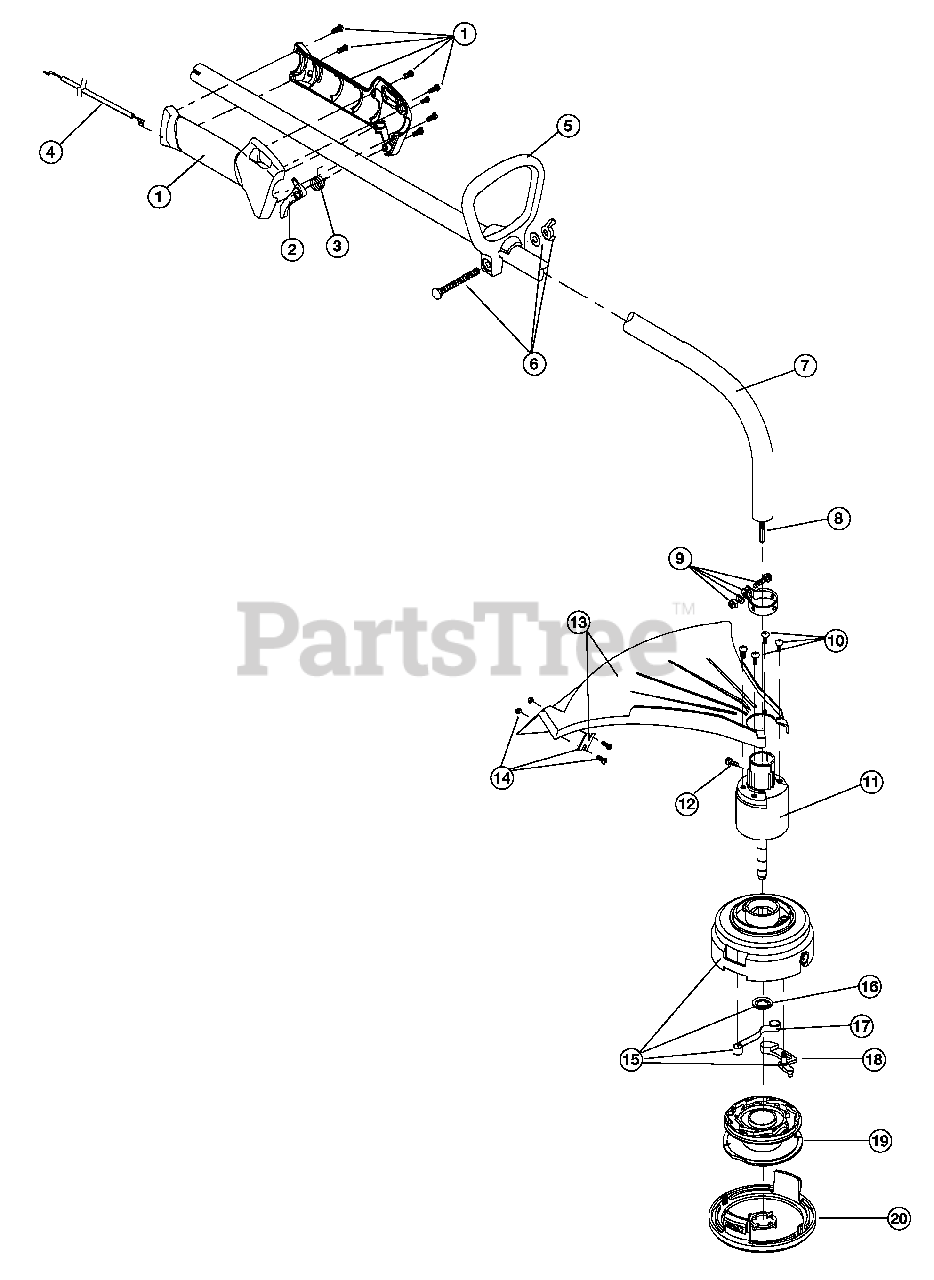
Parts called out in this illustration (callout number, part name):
1	Throttle Housing & Trigger Assembly (includes 2 & 3)
2	Throttle Trigger Spring
3	Throttle Trigger
4	Throttle Cable Assembly
5	D-Handle Assembly (includes 6)
6	D-Handle Hardware
7	Drive Shaft Housing Assembly
8	Flexible Drive Shaft
9	Lower Clamp Assembly (includes 12)
10	Shield Mounting Screw
11	Bushing Housing Assembly w/shaft (For ALF Head)
11	Housing
12	Anti-Rotation Screw
13	Shield and Blade Assembly (includes 14)
14	Blade Assembly
15	Outer Spool w/ Retainer (includes 16-18)
16	Retainer
17	Pawl Spring
18	Ratchet Pawl
19	Inner Reel
20	Spool Cover
